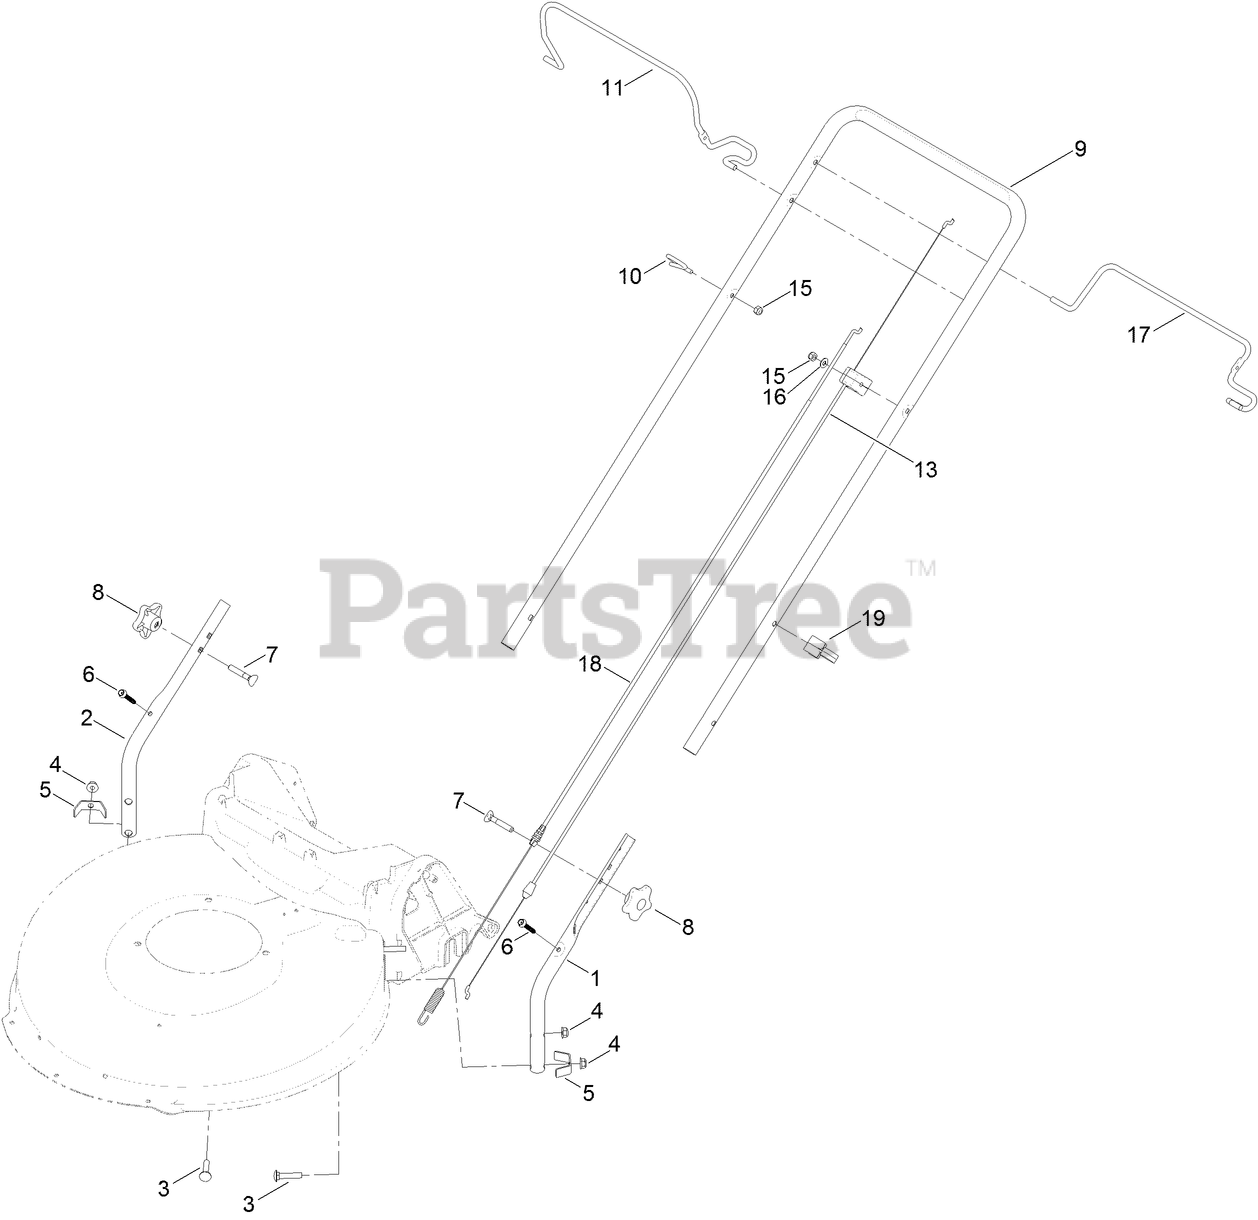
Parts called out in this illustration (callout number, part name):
1	HANDLE-LOWER, LH
2	HANDLE-LOWER, RH
3	BOLT-CARR
4	NUT-FLANGE, NI
5	BRACKET-CHUTE
6	SCREW-FLANGE, SERRATED
7	SCREW-HANDLE
8	KNOB-HANDLE
9	HANDLE-UPPER
10	GUIDE-ROPE
13	CABLE-BRAKE
15	NUT-LOCK, NI
16	WASHER-FLAT
17	BAIL-TRACTION
18	CABLE-TRACTION
19	GUIDE-CABLE
